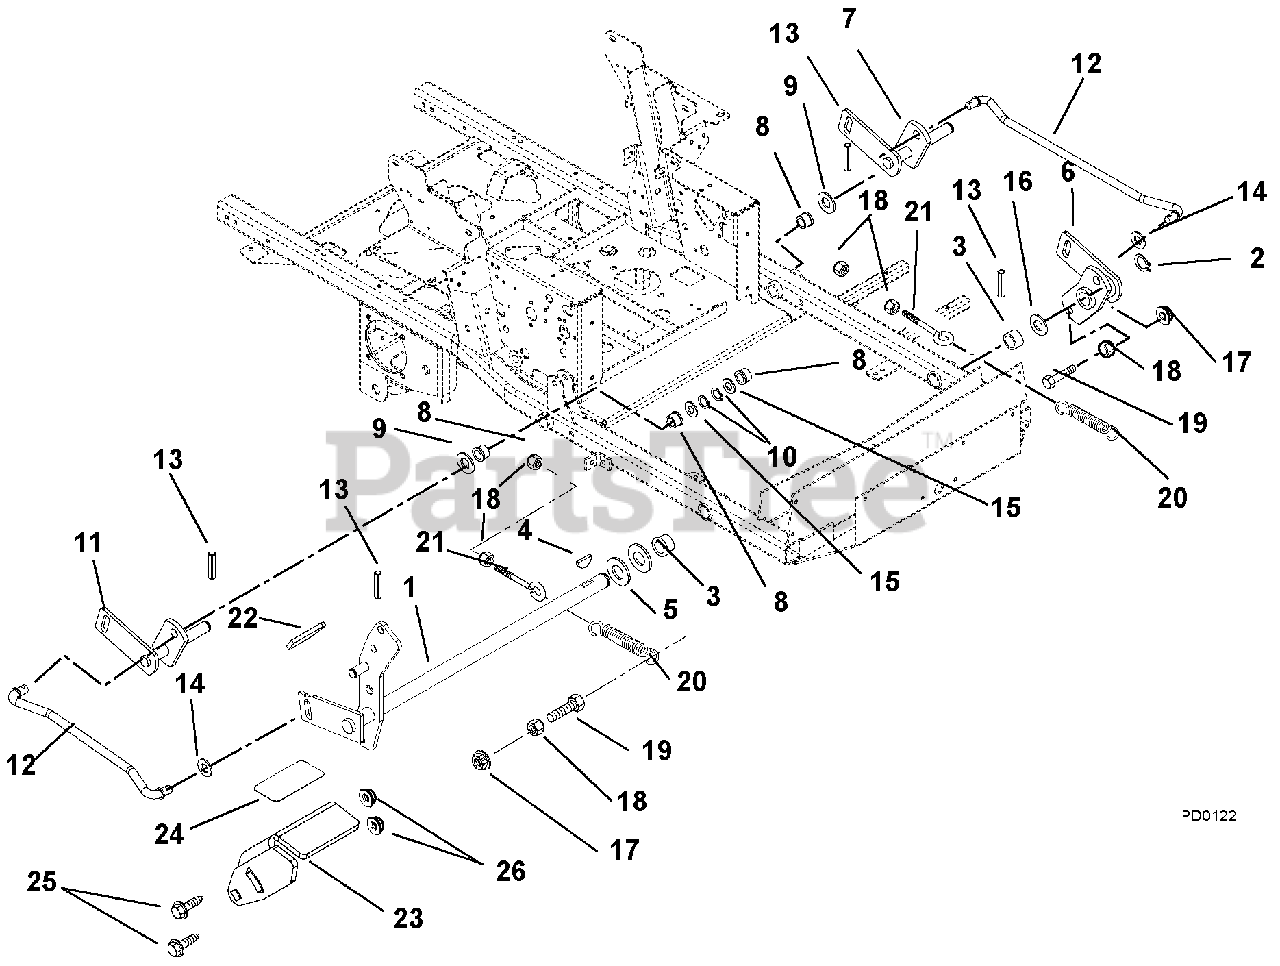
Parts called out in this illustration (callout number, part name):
1	Lift, Mechanical Mower (992210, 212)
2	Ring, Retaining External 1.00 x .078
3	Bushing, 1.00 x 1.12 x .75 x 1.375
4	Key, Woodruff .25 x 1.00
5	Washer, Flat Steel 1.062 x 2.00 x .134
6	Weldment, Lift Arm Front
7	Weldment, Left Hand Rear Lift Arm
8	Bushing, Flange Nylon .762 x 1.00 x .58 x 1.48
9	Washer, Hardened Steel .758 x 1.23 x .031
10	Ring, Retaining External .689 x .077
11	Weldment, Right Hand Rear Lift Arm
12	Rod, Lift Assist
13	Pin, Roll .250 x 1.25 Stainless Steel
14	Washer, Flat Steel .630 x 1.25 x .062
15	Washer, Flat Steel .812 x 1.50 x .135
16	Washer, Hardened Thrust 1.00 x 1.55 x .03
17	Nut, Locking Top Flange .38-16 (992210, 212)
18	Nut, Hex .38-16 (992210, 212)
19	Bolt, Hex .38-16 x 1.75 Grade 5 (992210, 212)
20	Spring, Tension .162 x 1.25 x 8.25 (992210, 212)
21	Bolt, Eye .375-16 x 2.50 (992210, 212)
22	Grip, Foot Pedal (992210, 212)
23	Pedal, Foot Lift Adjustable (992210, 212)
24	Grip, Foot Pedal (992210, 212)
25	Bolt, Round Hd. Square Neck .50-13 x 1.50 (992210, 212)
26	Nut, Lock Nyloc Flange .50-13 (992210, 212)
